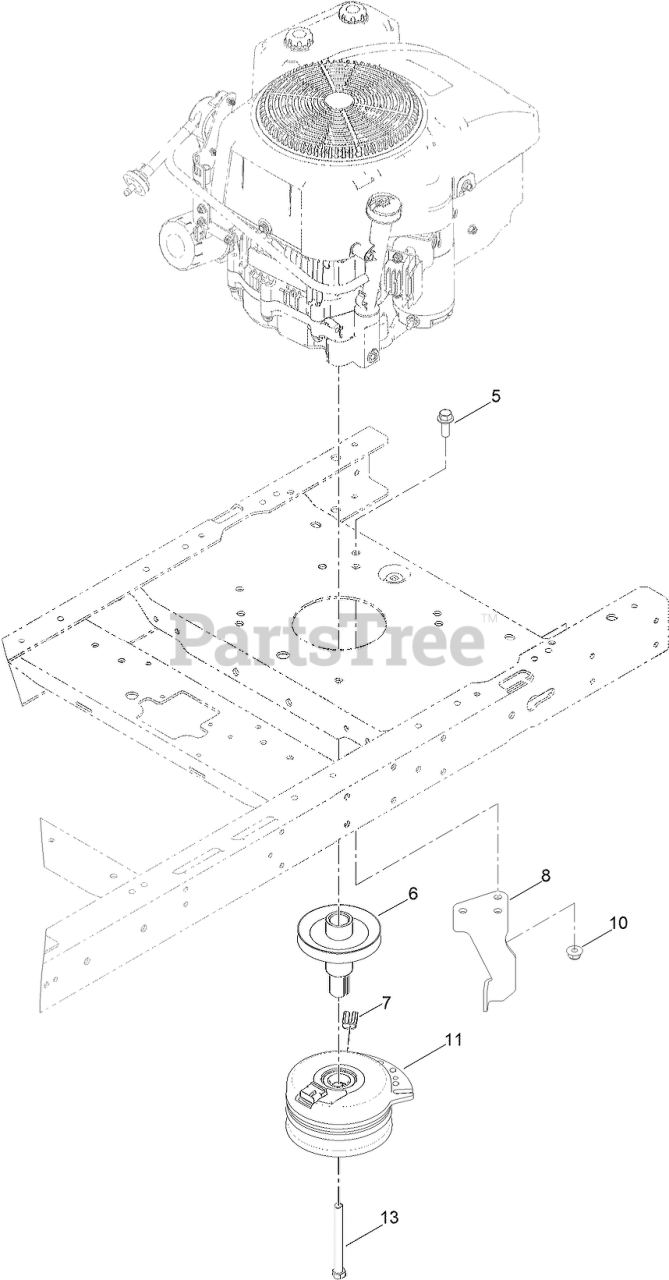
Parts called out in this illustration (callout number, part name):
5	SCREW-HHF
6	PULLEY-ENGINE
7	ISOLATOR-CLUTCH
8	STOP-CLUTCH
10	NUT-HF, NI
11	CLUTCH-ELECTRIC
13	SCREW-HH
